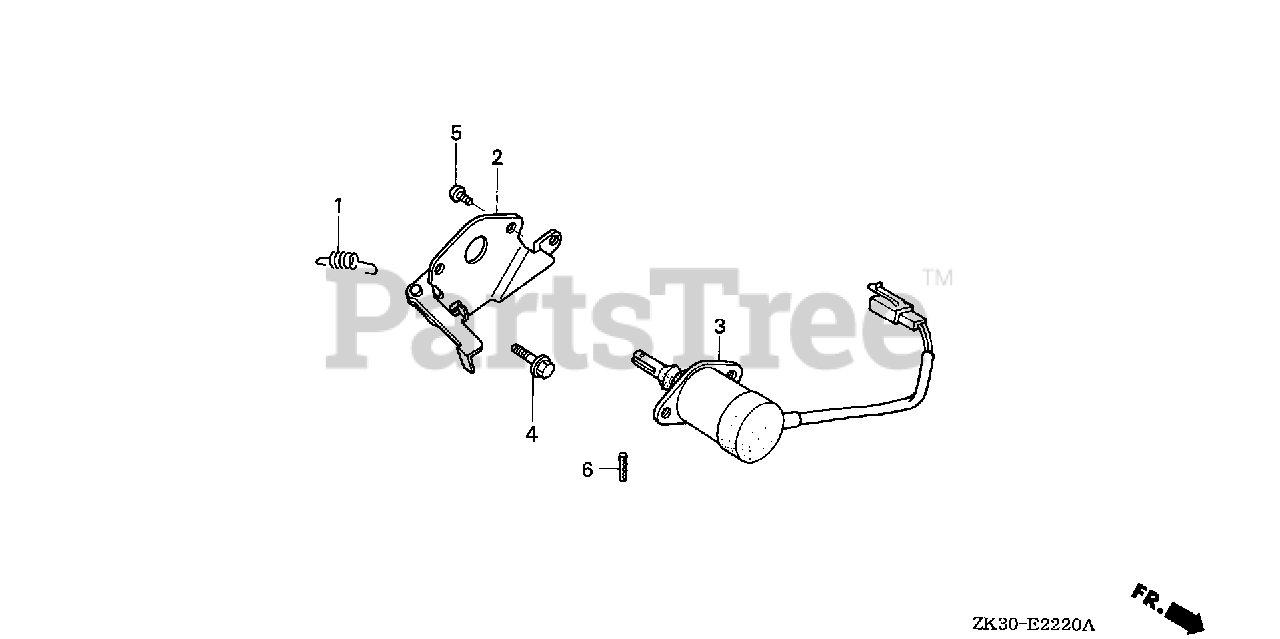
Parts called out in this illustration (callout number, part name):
1	SPRING, CHOKE RETURN
2	LEVER, THROTTLE
3	SOLENOID ASSY.
4	BOLT, FLANGE (6X12) (CT200)
5	SCREW, PAN (5X8)
6	PIN, SPRING (2X6)
